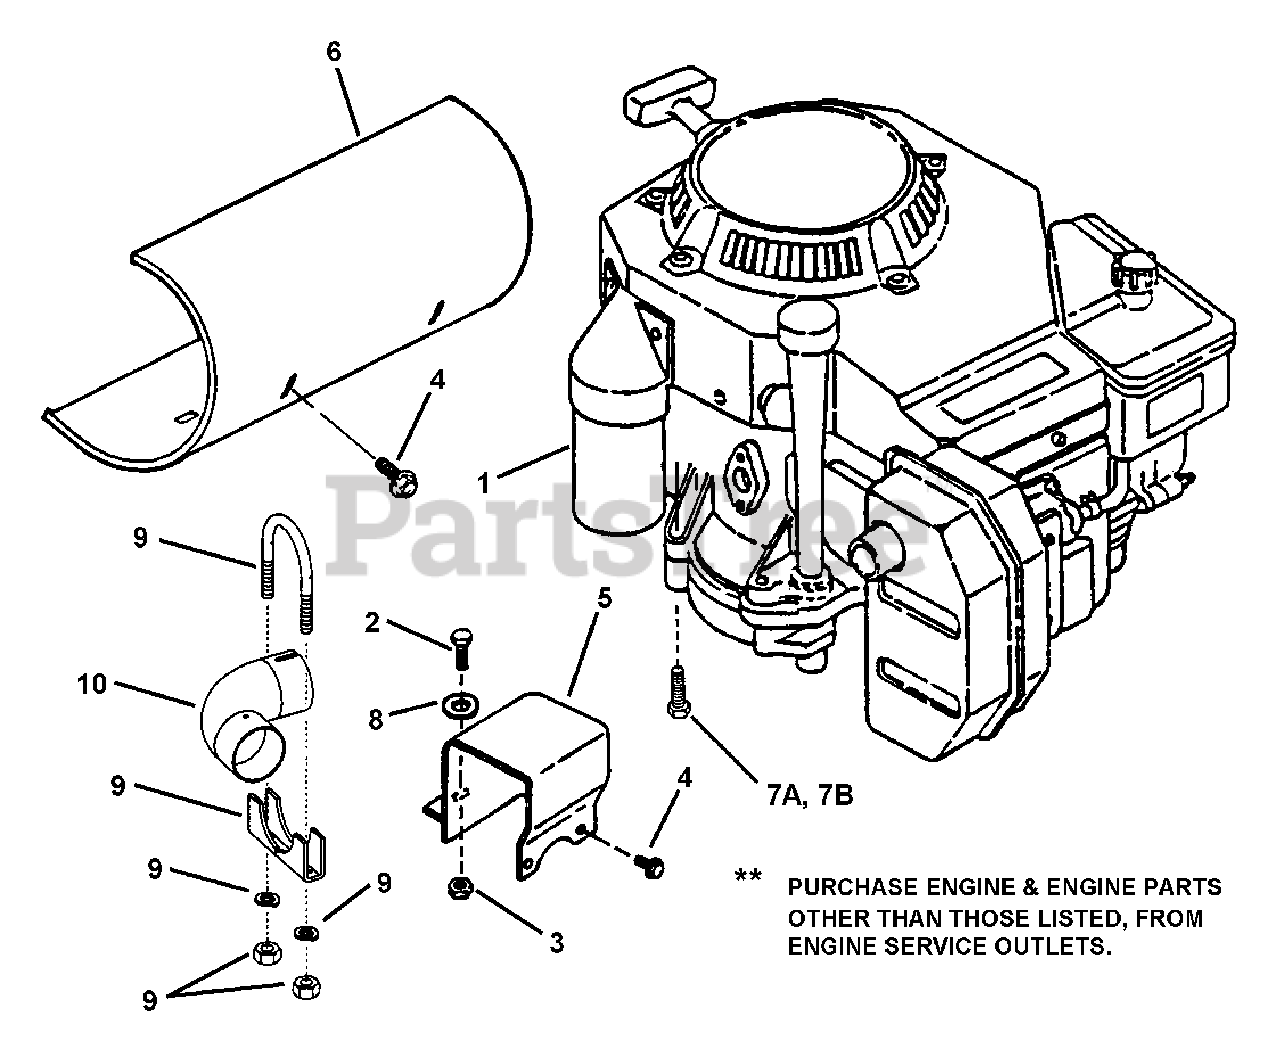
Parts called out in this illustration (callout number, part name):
2	SCREW #10-24 x 1/2" Hex Head Machine
3	NUT, #10-24 Hex Center Lock
4	SCREW, #8-18 x 9/16"
5	SHIELD, Heat
6	SHIELD, Heat
7A	BOLT, M8-1.25 X 25MM GD8.8
7B	SCREW, 5/16-18 x 1-1/2", Grade 5
8	WASHER, #10 Flat
9	ASSEMBLY, Clamp
10	ELBOW, Exhaust
